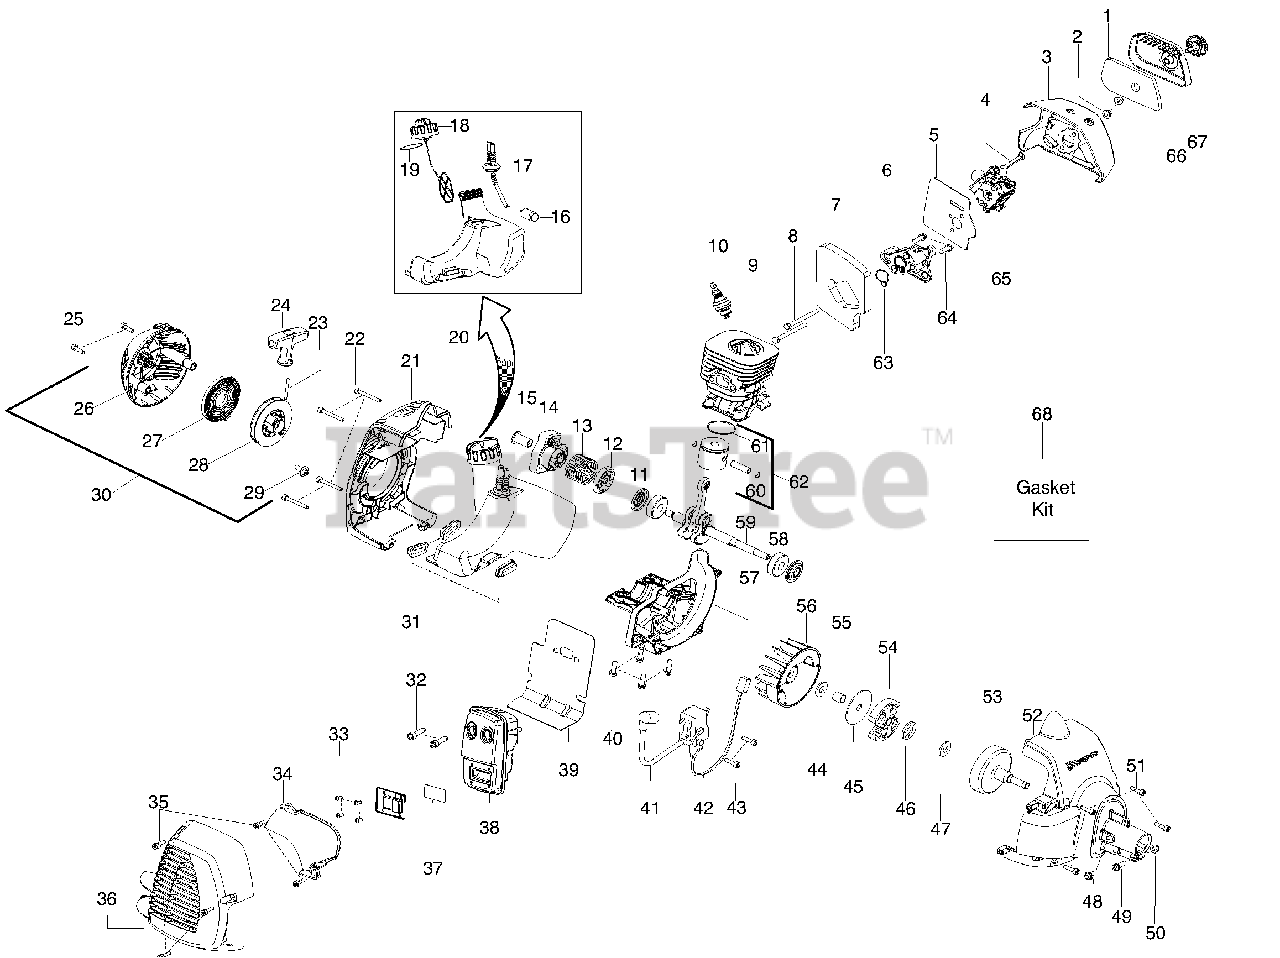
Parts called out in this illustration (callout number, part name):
2	Nut-Carb. Screw
3	Air Box
4	Lever - Choke
5	Kit-Carb. Gasket
6	Adaptor-Carb.
7	Kit-Gasket (foam)
9	Cylinder
10	Plug-Spark (RCJ-8Y)
11	Kit-Crankshaft seal
12	Washer-Starter
13	Spring-Starter Cup
14	Assy-Starter Cup
15	Coupling-Starter
16	Assy-Fuel Filter
17	Kit-Fuel Line
18	Assy-Cap w/ret.
19	Kit-Gasket O-ring - Fuel Cap
20	Assy-Fuel Tank
21	Shroud-Rear
24	Handle-Starter
26	Starter Hsg. w/eyelet
27	Kit-Starter Spring
28	Kit-Starter Pulley
30	Assy-Starter Hsg.
31	Isolator-Tank
32	Bolt-Muffler
34	Shield-Heat
36	Guard-Muffler
37	Kit-Spark
38	Assy-Muffler
39	Kit-Gasket-Paper Met.
42	Assy-Leadwire
45	Washer-Clutch
46	Bearing - Thrust
47	Washer - Thrust
52	Assy-Fan Housing
53	Assy-Clutch Drum
54	Kit-Clutch Assy.
59	Kit-Crankshaft
60	Retainer-Piston Pin
61	Ring-Piston
62	Kit-Piston
63	Kit-Gasket (adaptor seal)
65	Kit-Carb.
66	Cover-Air Box
68	Kit-Gasket
